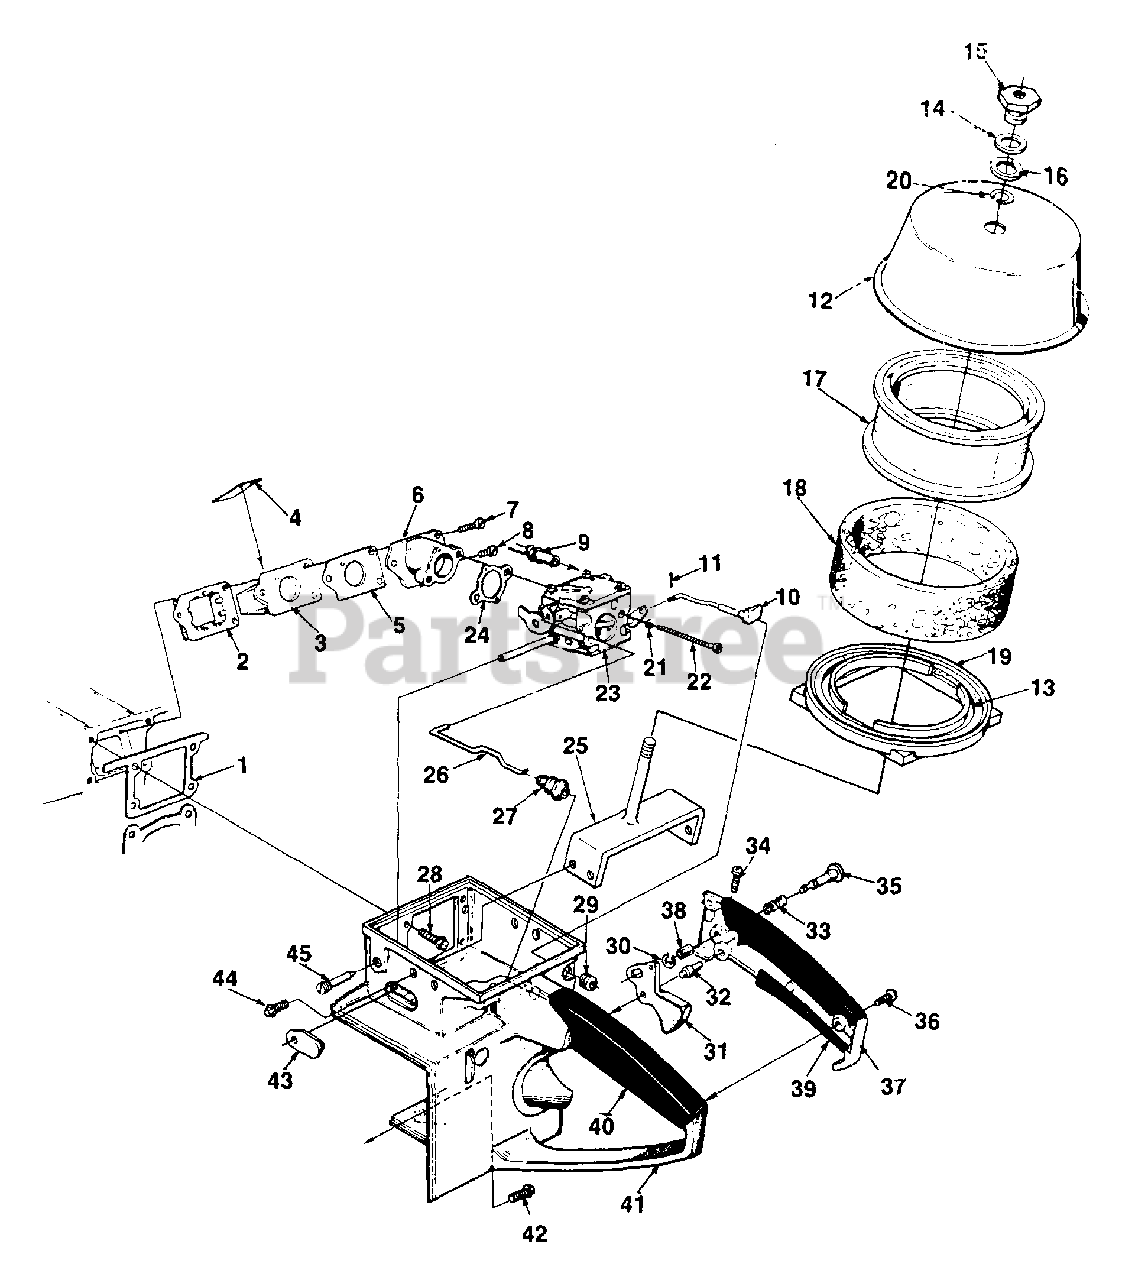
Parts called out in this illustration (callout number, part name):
2	RETAINER-Reed
3	SEAT-Reed valve
4	REED-Valve
6	SPACER-Carburetor
7	SCREW-Pan hd. 8-32 x 1 1/4
8	SCREW-Pan hd. 8-32 x 1
9	FUEL LINE
10	CHOKE ROD
11	COTTER PIN
12	AIR FILTER COVER
17	FILTER ELEMENT-Air
18	FILTER ELEMENT-Air (Foam)
19	RING & GASKET ASSEMBLY
20	RING-Retaining
21	WASHER-Lock
22	SCREW-10-32 x 1 7/8
23	CARBURETOR
25	BRACKET-Cover
26	ROD-Throttle
27	BOOT-Throttle rod
28	SCREW-Hex hd. 12-24 x 5/8
29	GROMMET
31	TRIGGER
34	SCREW-8-32 x 5/8
35	PIN-Throttle
36	SCREW-Pan hd. 8-32 x 1/2
37	COVER-Throttle handle
38	BUSHING
39	GRIP-Throttle handle cover
40	GRIP-Throttle handle
41	HANDLE-Throttle
42	SCREW-Hex hd. 12-24 x 7/8
43	GROMMET
44	SCREW-Pan hd. 8-32 x 1/4
45	SCREW
